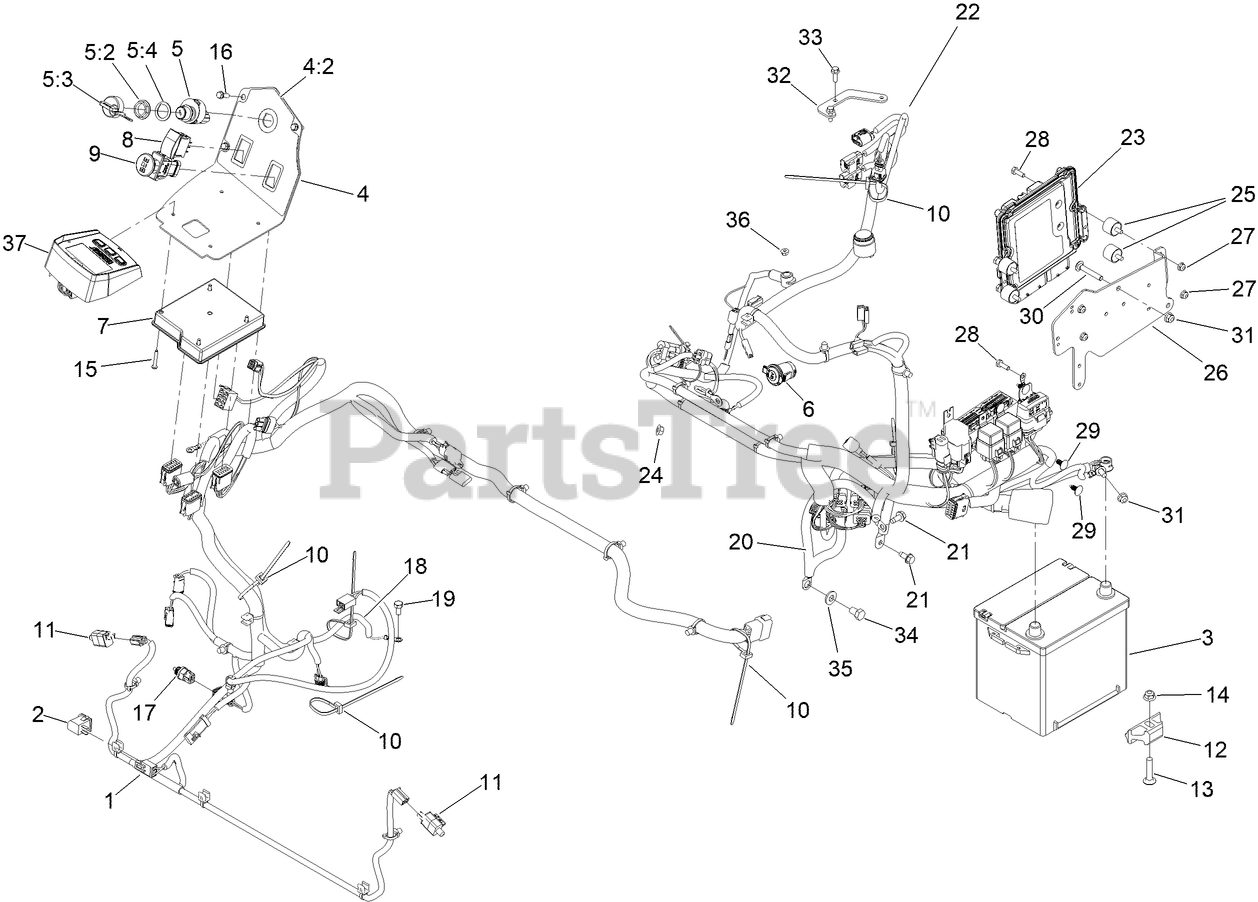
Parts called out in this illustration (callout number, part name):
1	HARNESS-WIRE
2	SWITCH-BAIL
3	BATTERY-DRY
4	CONSOLE ASM
4:2	DECAL-CONSOLE
5	IGNITION SWITCH ASM
5:2	NUT-MOUNTING
5:3	IGNITION KEY SET
5:4	WASHER-BACKUP
6	PORT-POWER, 12V
7	MODULE-MCU
8	SWITCH
9	SWITCH-PTO, SEALED
10	TIE-CABLE
11	SWITCH
12	RETAINER-BATTERY
13	SCREW-CARR
14	NUT-HF, NI
15	SCREW-PPH
16	SCREW-HWH
17	SENSOR-TEMPERATURE
18	HARNESS-WIRE, JUMPER
19	BOLT
20	CABLE-BATTERY
21	SCREW-HWHTF
22	HARNESS-WIRE, YANMAR
23	CONTROLLER-ENGINE
24	NUT-HF
25	MOUNT-CYLINDRICAL
26	MOUNT-CONTROL UNIT, ENGINE
27	NUT-HF
28	SCREW-HH
29	PLUG-PLASTIC
30	BOLT-CARR
31	NUT-HF, NI
32	BRACKET-WIRING, ENGINE
33	SCREW-HHF
34	SCREW-HH
35	WASHER-BELLEVILLE
36	NUT-HF
37	MODULE-HORIZON
